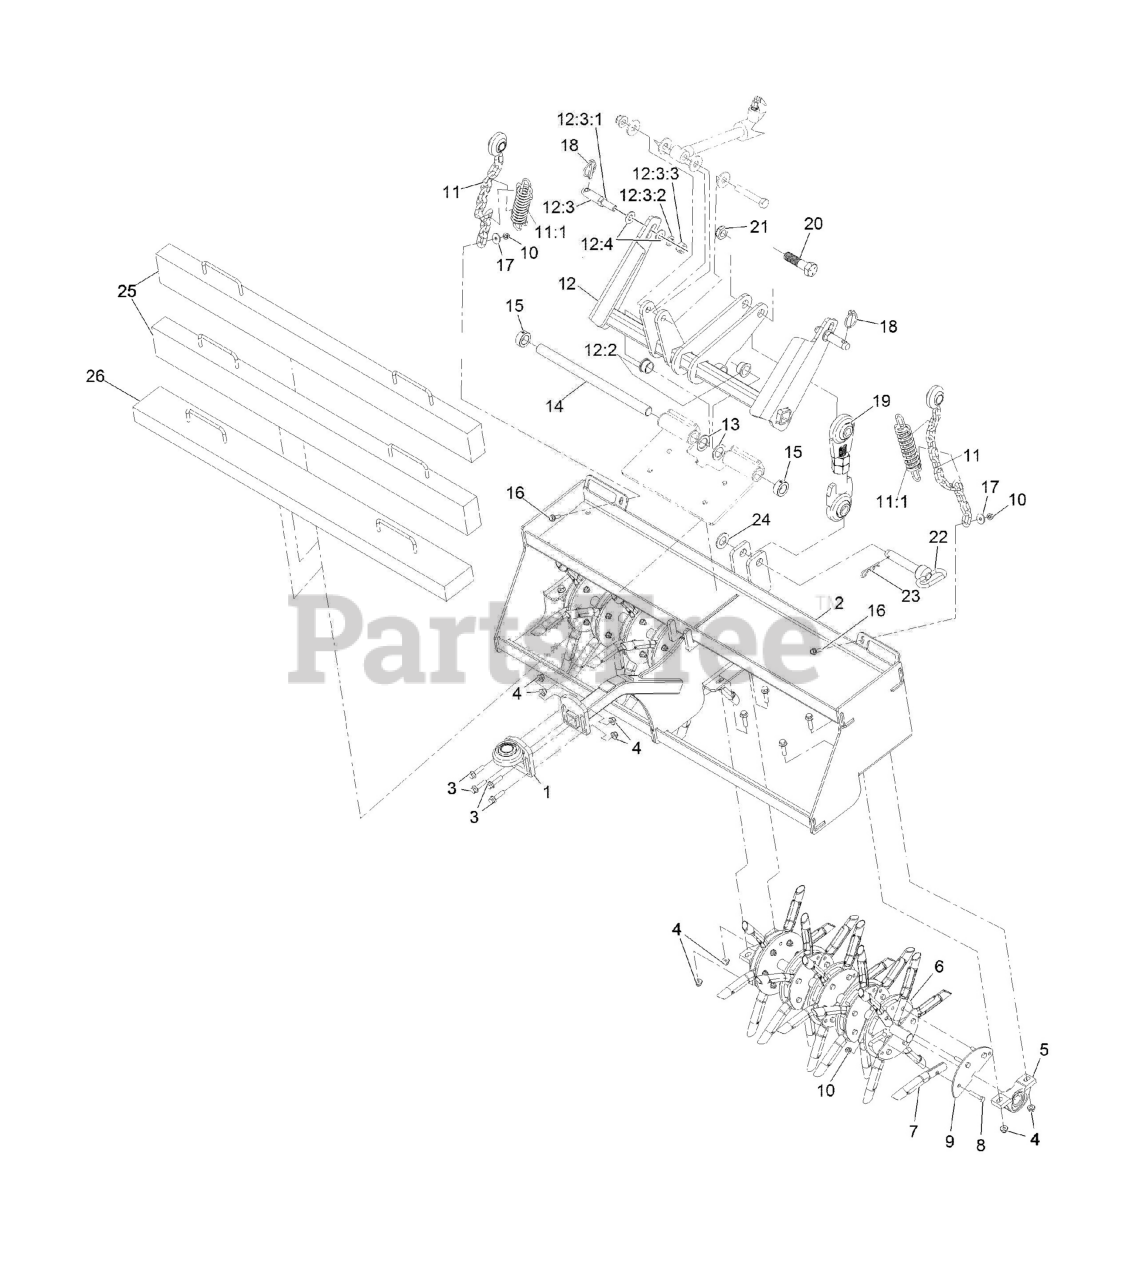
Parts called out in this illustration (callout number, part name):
1	MOUNT-SWIVEL BRG,AER HEAD
2	HEAD-AERATION, 40""
3	SCREW-HHF
4	NUT-HF, NI
5	PILLOW BLOCK BEARING
6	REEL-TINE
7	TINE-CORING (3/4 INCH)
8	SCREW-HH
9	DISK, HALF, AE
10	NUT-HF, NI
11	SWIVEL-CHAIN ASM
11:1	Z-PLUG DRAWBAR SPRING
12	ARM-LIFT, ASM
12:2	BUSHING-FLANGE
12:3	7/8 X 4-1/2 LIFT PIN\N21
12:3:1	NUT-JAM
12:3:2	WASHER-LOCK
12:3:3	NUT-HEX
12:4	WASHER-FLAT
13	WASHER-THRUST
14	PIVOT-LIFT ARM
16	SCREW-HH
17	WASHER-FLAT
18	PIN-LYNCH
19	BALL SWIVEL, ADUSTABLE LI
20	7/8-9 X 3-1/4 GR8 HEX CAP
21	NUT-LOCK, NI
22	7/8 X 4 HITCH PIN RED HAN
23	PIN-HAIR
24	WASHER-FLAT
25	112LBS WEIGHT\N45.25
26	WEIGHT-HORIZ, ZPLUG
